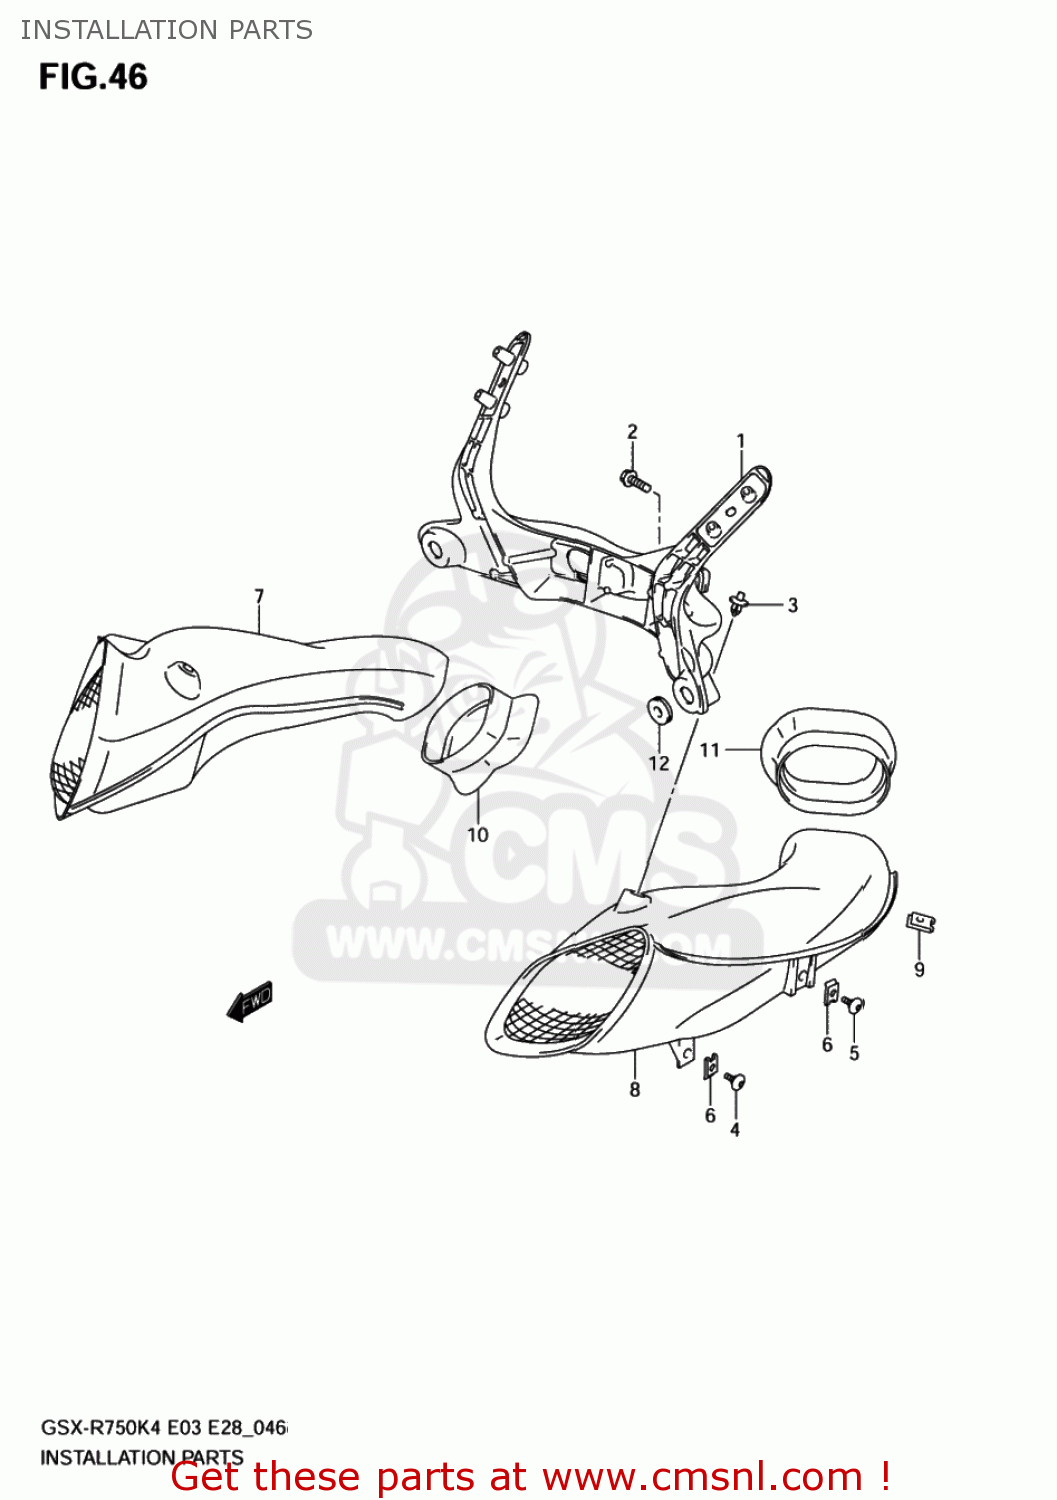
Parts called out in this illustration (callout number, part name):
1	BRACE,COWLING
2	BOLT
3	CLIP(BLACK)
4	SCREW(5X13)
5	SCREW(5X16)
6	NUT,COWL
7	PIPE ASSY,AIR INTAKE,R
8	PIPE ASSY,AIR INTAKE,L
9	NUT,COWL
10	MOLDING,AIR INTAKE,R
11	MOLDING,AIR INTAKE,L
12	CUSHION
